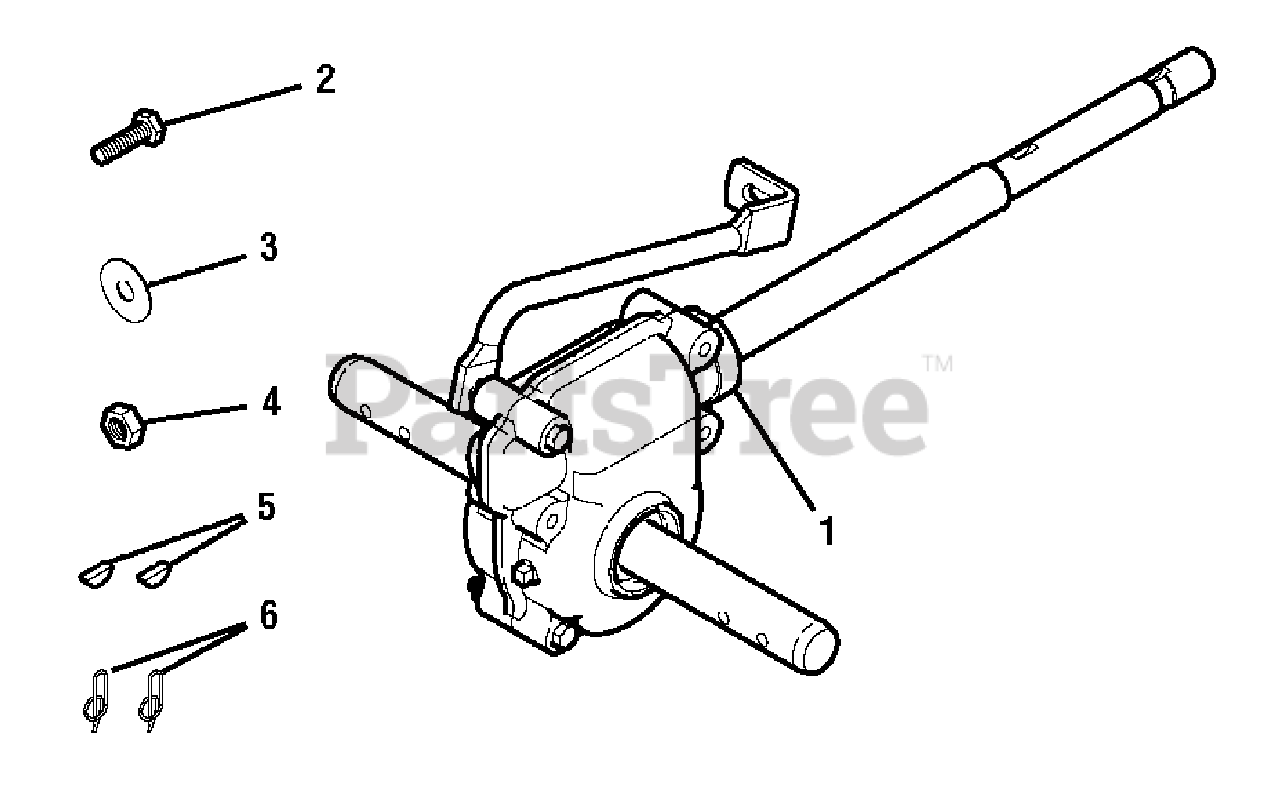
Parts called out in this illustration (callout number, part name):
1	Gear Box
2	Capscrew, 5/16-18 x 3/4
3	Washer, Flat 5/16
4	Nut, Nylock, 5/16-18
5	Key, Woodruff
6	Pin, Cotter, Self-locking
